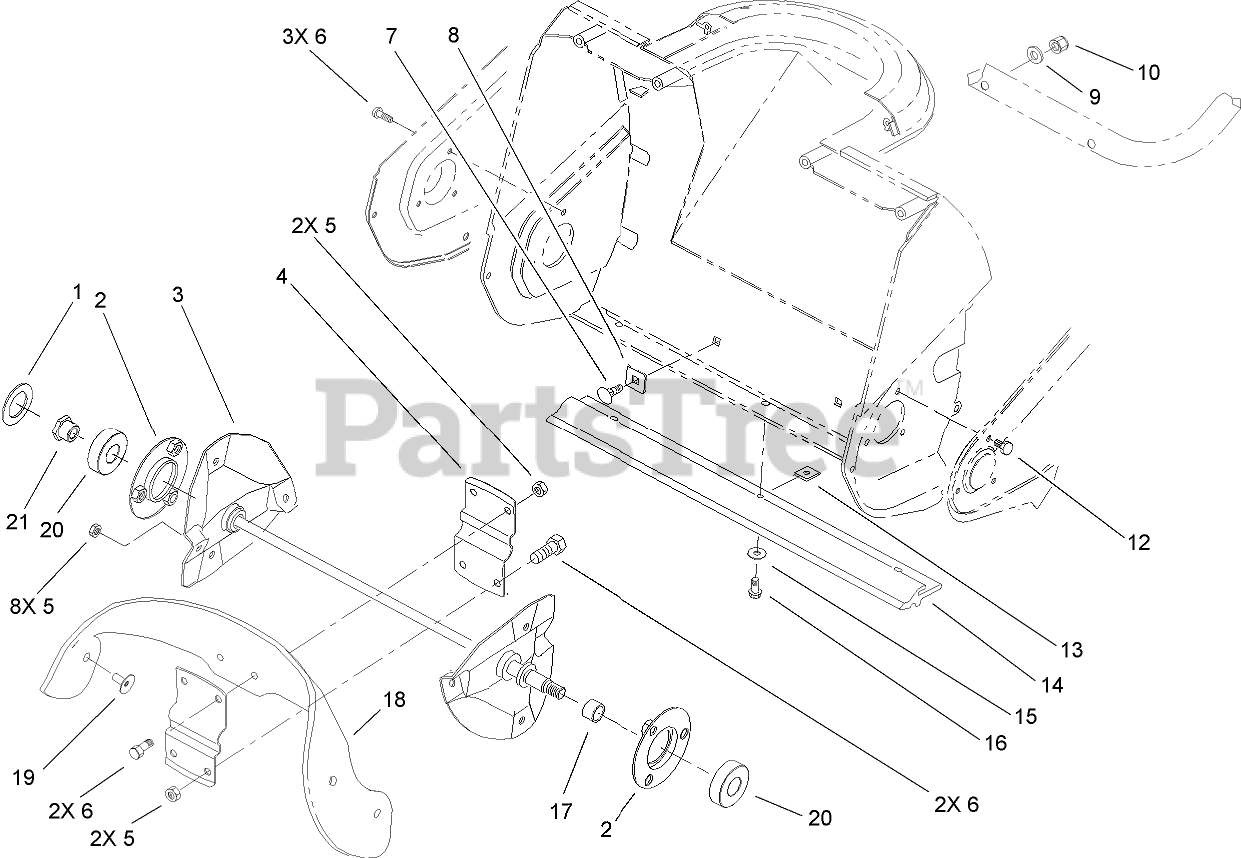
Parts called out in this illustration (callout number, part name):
1	WASHER-RUBBER
2	FLANGE BEARING ASM
3	ROTOR SHAFT ASM
4	SUPPORT-ROTOR
5	NUT-LOCK, NI
6	SCREW-HHF
7	SCREW-CARR
8	WASHER-SQUARE
9	WASHER
10	NUT-LOCK, NI
12	SCREW-HH
13	NUT-CLIP, U
14	SCRAPER
15	WASHER-FLAT
16	SCREW-HWHTF
17	SPACER
18	BLADE-ROTOR
19	SCREW
20	BEARING-BALL
